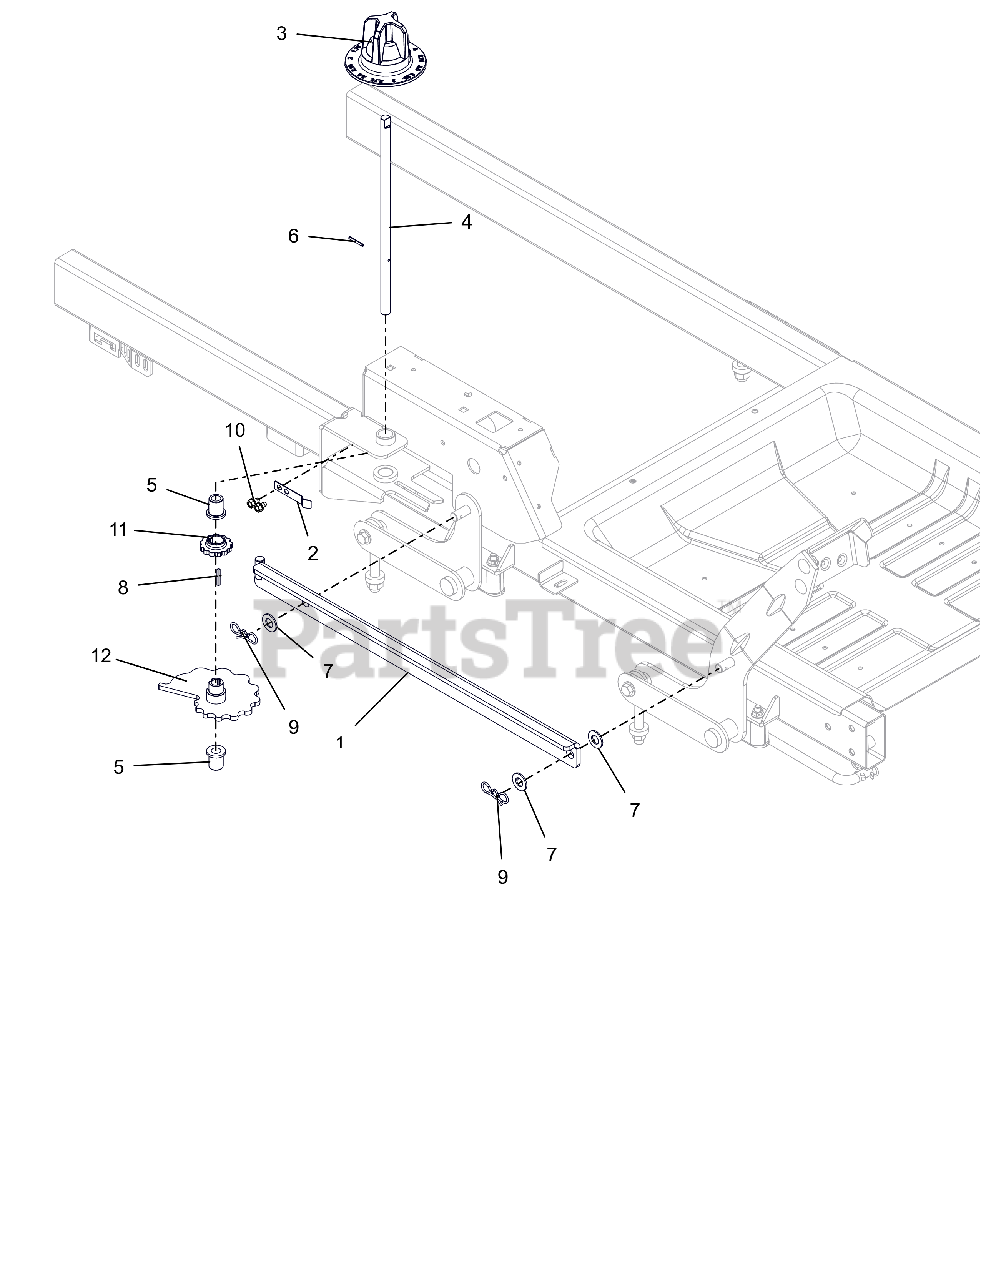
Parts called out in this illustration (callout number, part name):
1	WLDMT, HOC LINK
2	ARM, HOC DETENT
3	KNOB, HOC DIAL
4	SHAFT, HOC CAM IKON
5	BSHG-FLG, .503X.750X.875X1.00
6	PIN-ROLL .125X1.00
7	WSHR-FL-NYL .518X1.000X.080
8	KEY, 1/8 X 1/8 X 1.0
9	PIN,BOW TIE LOCKING .091X1.875
10	SCR,TAP .25-20X.375 HWH TR ZCC
11	GEAR, HOC INDEX
12	WLDMT, HOC CAM
